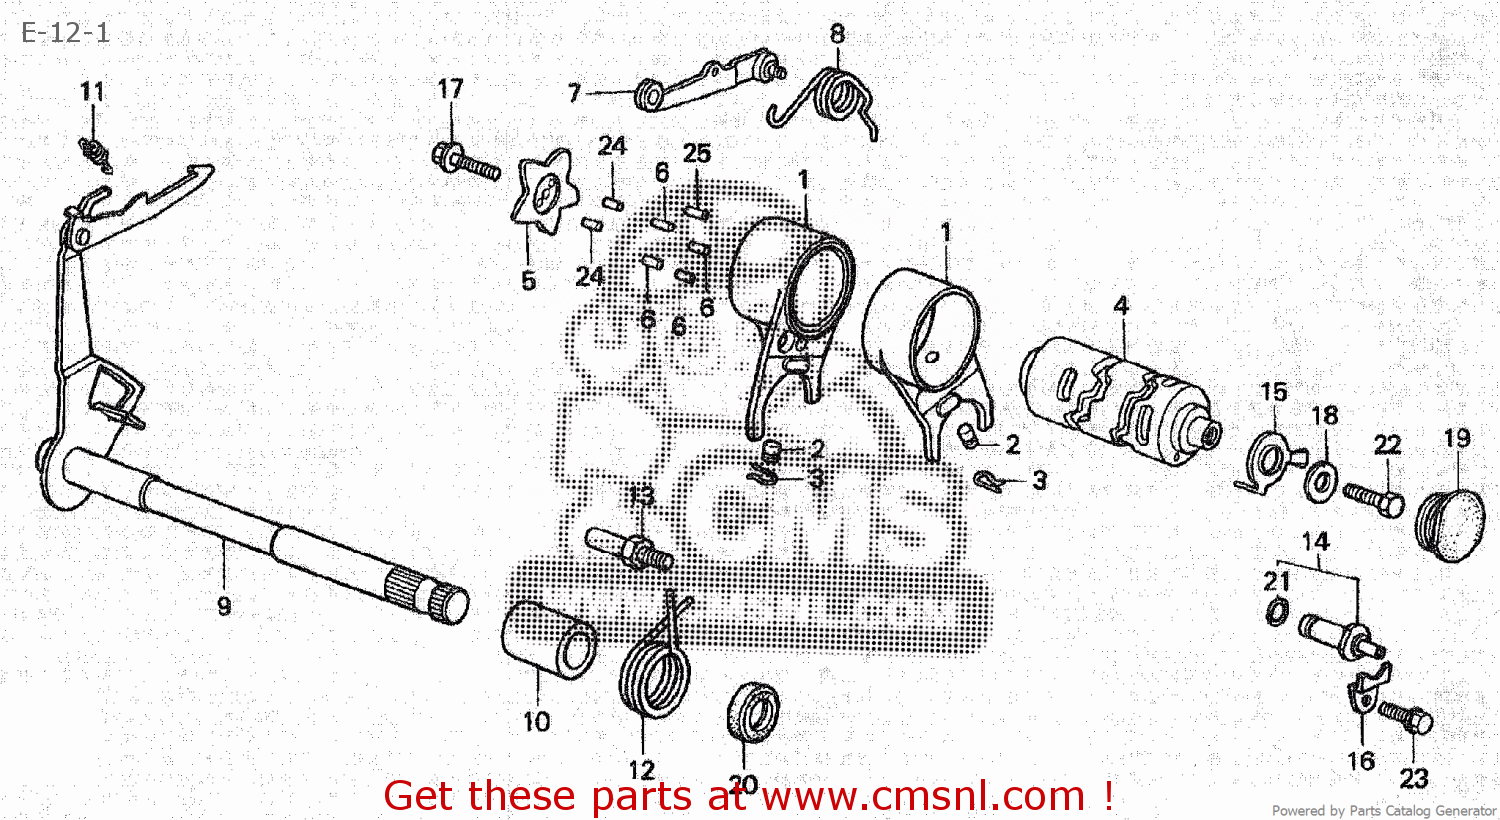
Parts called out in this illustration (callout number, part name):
1	FORK,GEAR SHIFT
2	PIN,GEAR SHIFT FO
3	CLIP, SHIFT FORK
4	DRUM GEAR SHIFT
5	PLATE SHIFT DRUM
6	PIN,GEARSHIFT
7	ARM,SHIFT DRUM ST
8	SPG.SHIFT DRUM ST
9	SPINDLE COMP,GEAR
10	COLLAR,12.2
11	SPRING,SHIFT ARM
12	SPRING SHIFT RTN
13	PIN, SHIFT RETURN
14	CONTACT,NEUTRAL
15	ROTOR,NEUTRAL SW
16	PLATE
17	BOLT,NOCK,6MM
18	WASHER, DRUM
19	PLUG, RUBBER
20	OIL SEAL
21	O-RING 7X1.7
22	BOLT,HEX.,6X16
23	BOLT,FLANGE,6X12
24	ROLLER 3X8.5
25	ROLLER,4X10
